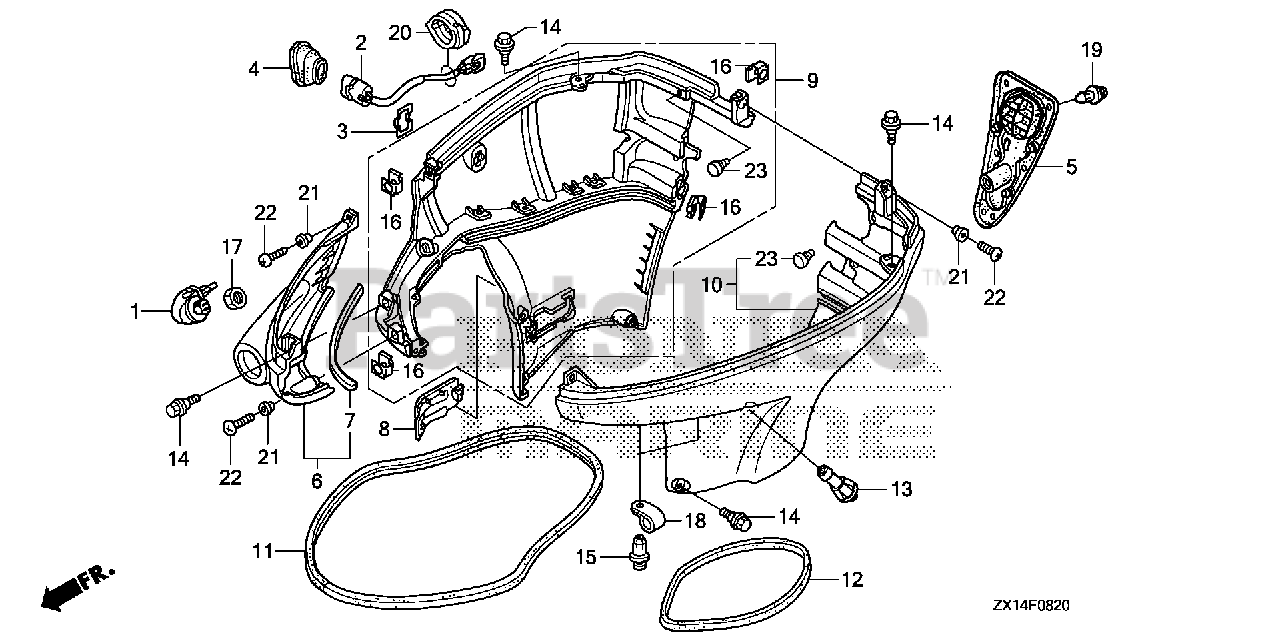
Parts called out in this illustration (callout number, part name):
1	CAP, WATER JOINT
2	SWITCH ASSY., POWER TILT
3	STAY, POWER TILT SWITCH
4	GROMMET, POWER TILT SWITCH
5	GROMMET, COVER (LOWER)
6	COVER, FR. SEPARATE *NH282MU* (OYSTER SILVER METALLIC-U)
7	SEAL, FR. SEPARATE COVER
8	COVER, DRAIN PLUG *NH282MU* (OYSTER SILVER METALLIC-U)
9	COVER, R. ENGINE (LOWER) *NH282MU* (OYSTER SILVER METALLIC-U)
10	COVER, L. ENGINE (LOWER) *NH282MU* (OYSTER SILVER METALLIC-U)
11	SEAL A, COVER (LOWER)
12	SEAL B, COVER (LOWER)
13	GROMMET, WATER CHECK
14	BOLT, SPECIAL (6X17)
15	SCREW, RIVET (5X10)
17	NUT, HEX. (16MM) DUAL QTY = (2) (SINGLE)
18	CLIP (10.7MM)
19	CLIP, SPLASH GUARD
20	CLIP, WIRE HARNESS
21	COLLAR, DISTANCE (6.5X9X11.5)
22	SCREW, PAN (6X25)
23	RUBBER B, STAND STOPPER
